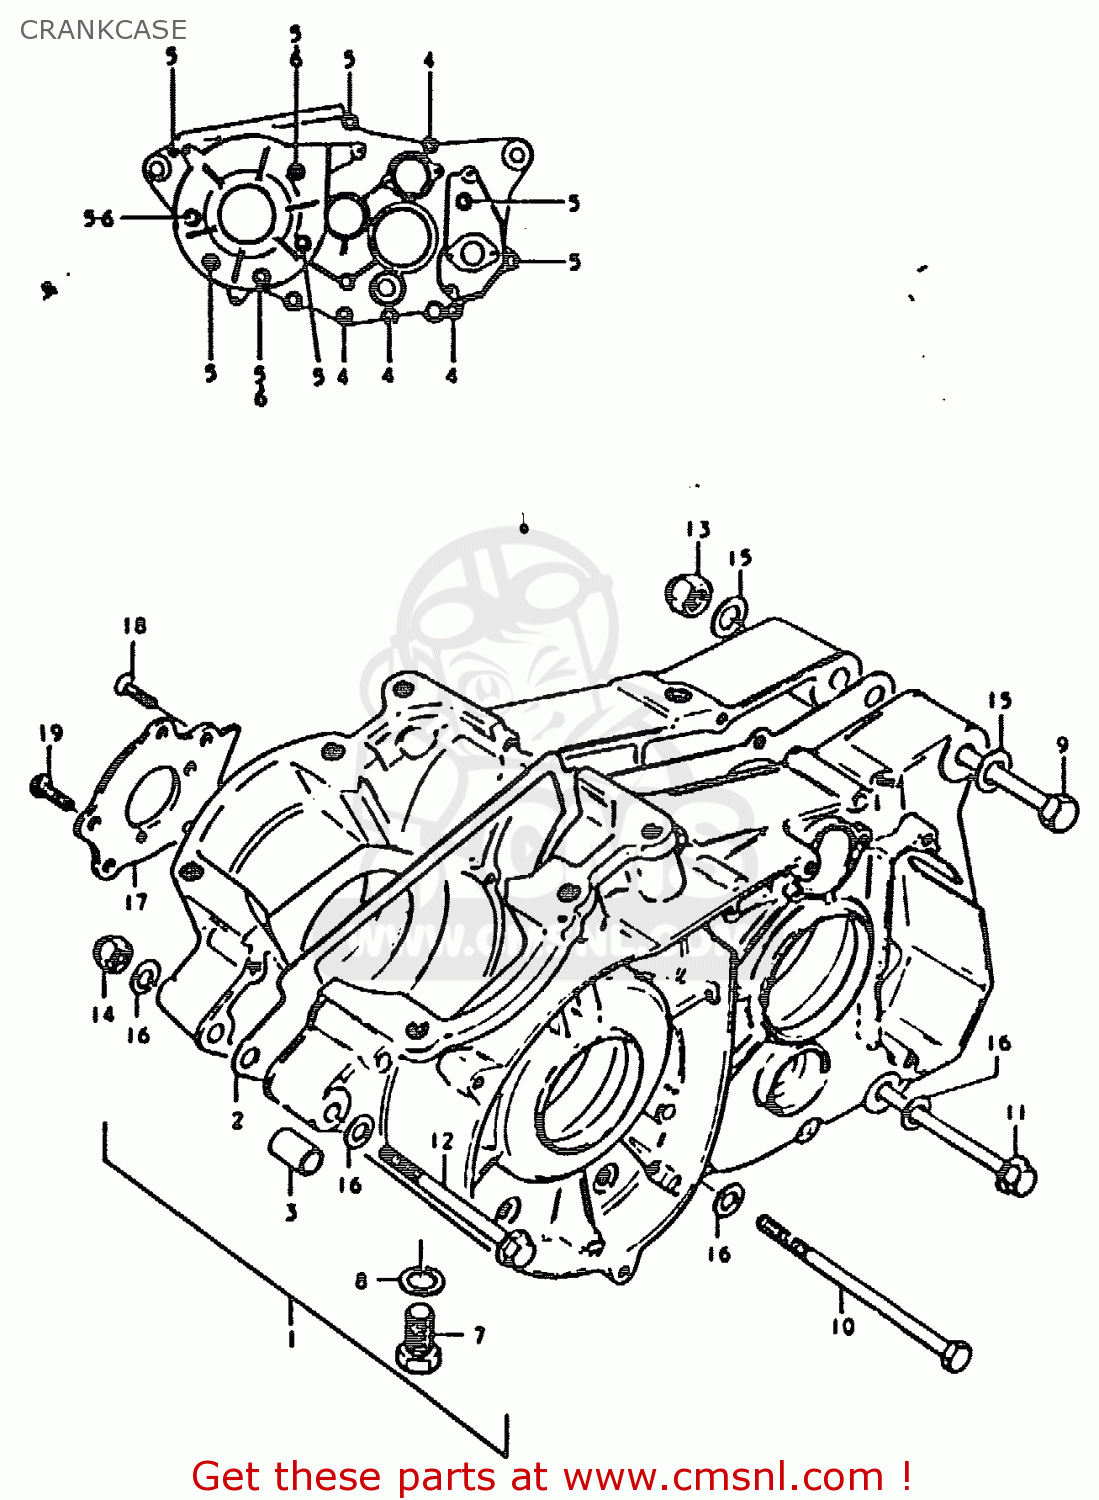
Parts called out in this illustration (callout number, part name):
1	CRANKCASE SET
2	GASKET,CRANKCASE (MCA)
3	PIN
4	SCREW 6X65
5	SCREW (6X45)
6	WASHER 6MM
7	PLUG
8	GASKET(14X19.2X2) (NAS)
9	BOLT
10	BOLT(8X145)
11	BOLT
12	BOLT
13	NUT
14	NUT
15	WASHER
16	WASHER
17	PLATE,OIL RESERVOIR
18	SCREW
19	SCREW
